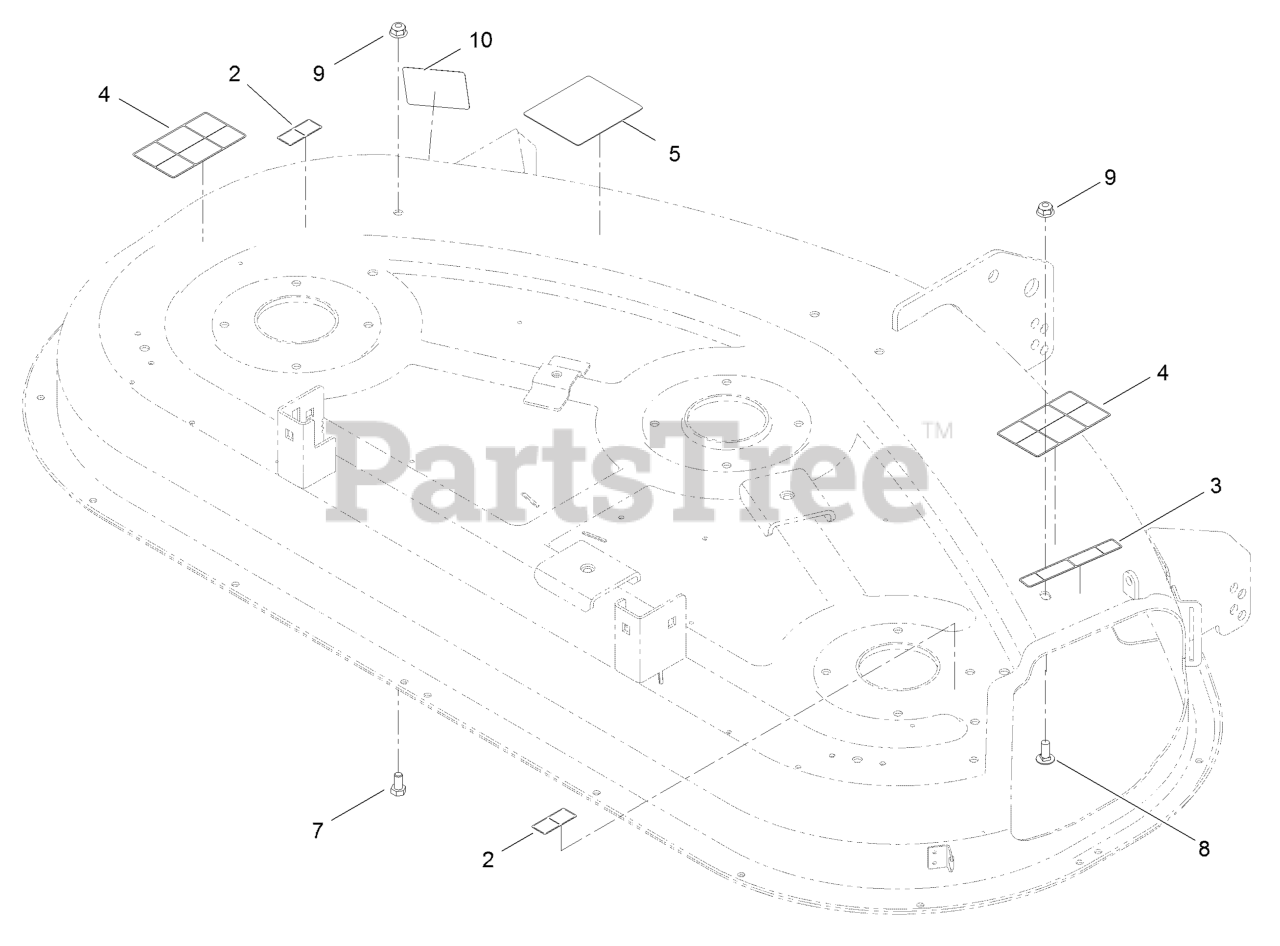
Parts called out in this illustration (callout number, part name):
2	DECAL-DANGER
3	DECAL-DANGER
4	DECAL-DANGER
5	DECAL-ROUTING, BELT
7	SCREW-HH
8	SCREW-CARR
9	NUT-HF, NI
10	DECAL-SCALP, ANTI
